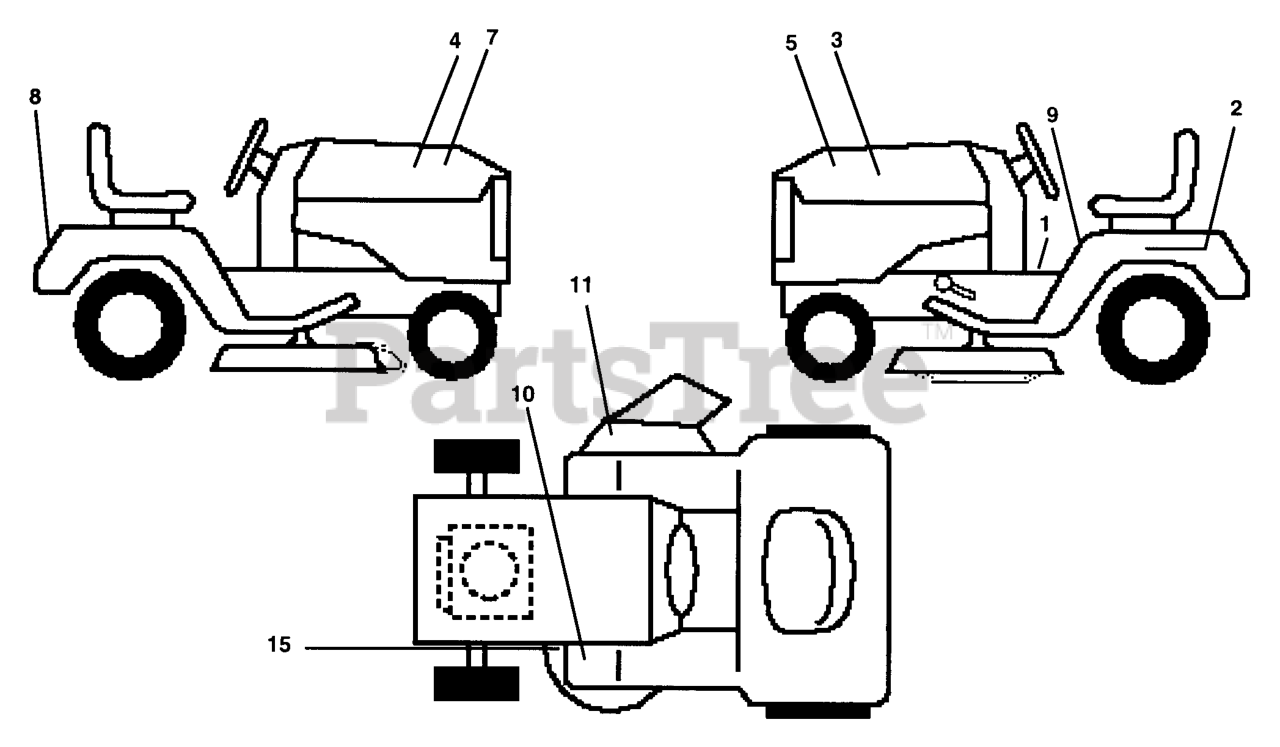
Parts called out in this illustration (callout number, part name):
1	DECAL DASH
3	DECAL HOOD RH
4	DECAL HOOD LH
5	Decal Ins Hd LH
7	Decal Ins Hd RH
8	DECAL FENDER NLA
9	DECAL CAUTION
11	DECAL WARNING (ENGLISH/FRENCH)
15	DECAL V-BELT SCHEMATIC
